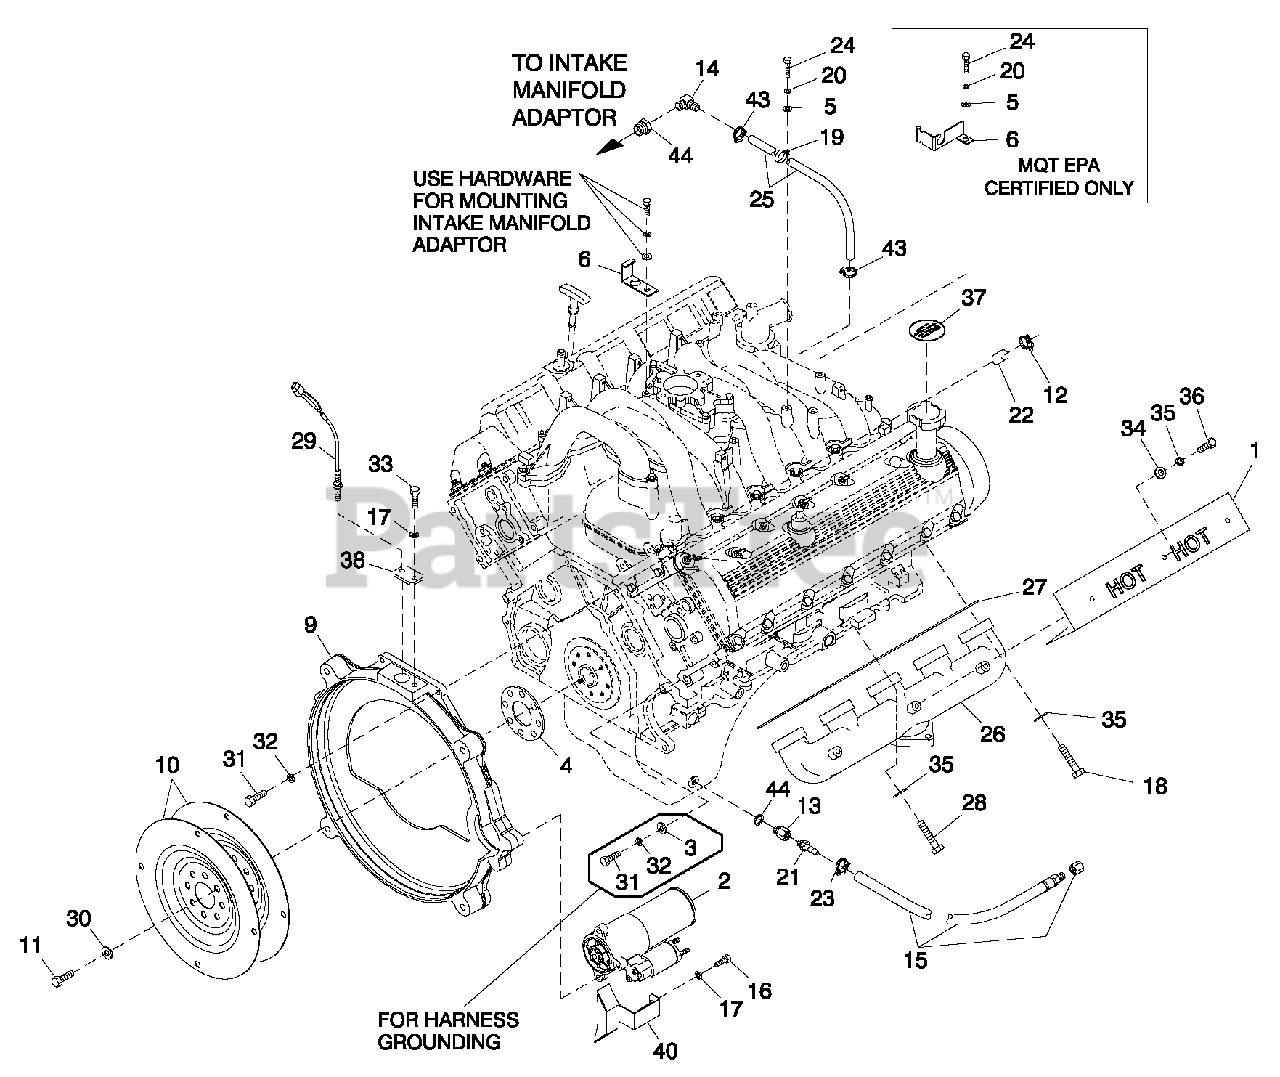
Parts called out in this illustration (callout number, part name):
1	HEAT SHIELD EXHAUST
2	STARTER MOTOR FORD V-10 ENGINE
3	WASHER FLAT3/8-M10ZINC
4	SPACER FLEXPLATE5.4L/6.8L(1800 RPMUNITS ONLY)
5	WASHER FLAT 1/4-M6ZINC
6	BRACKET SIGNAL CONDITIONER
7	TIE WRAP UL7.4" X .19" BLK
8	WASHER NYLON .565
9	ENGINE ADA PTER 54L/6.8L
10	FLEXPLATE 2 POLE (1800 RPM UNITS ONLY)
11	SCREW HHCM 10-1.0 X 25 G10.9
12	CLAM PHOSE #10.56 -1.06 (1800 RPM UNITSONLY)
13	ADAPTERM14-1.50 X3/8NPT
14	BARBED EL 90 3/8NPTX5/8
15	HOSE DRAIN ASSY 28"
16	SCREW HHCM 8-1.25X30 G8.8
17	WAS HER LOCK M8-5/16
18	SCREW SHC M8-1.25X35SS
19	CLAMP VINYL .75X.343Z
20	WAS HER LOCK M6-1/4
21	BARBED STR 3/8N PTX3/8
22	CAP HOSE (1800 RPM UNITS ONLY)
23	CLAM PHOSE .38-.87
24	SCREW HHCM6-1.0 X16G 8.8
25	HOSE COOL 5/8" ID 250#WP (14")
26	EXH MAN FOLD MACH 6.8L V-10
27	GASKET EXHAUST MANIFOLD
28	SCREW HHCM 8-1.25 X 35 SSG8.8
29	ASSY MAG PICK U P (3/8-24 MALE)
30	WAS HER FLAT. 43 X1.00
31	SCREW SHC M10-1.5X 25 G12.9
32	WAS HER LOCK M10
33	SCREW HHCM 8-1.25X20 G8.8
34	WAS HER FLAT M8 SS
35	WAS HER LOCK M8SSTL
36	SCREW HHC 916-18X 1/2 SSTL
37	DECAL REFER TO OWNERS MANUAL
38	PLATE MAGPICK-UPADAPTOR
40	COVER STARTER 54 & 6.8 FORD CPL
43	CLAM PHOSE #10.56-1.06
44	ADAPTOR 1/4' NPT TO 3/8" NPT
